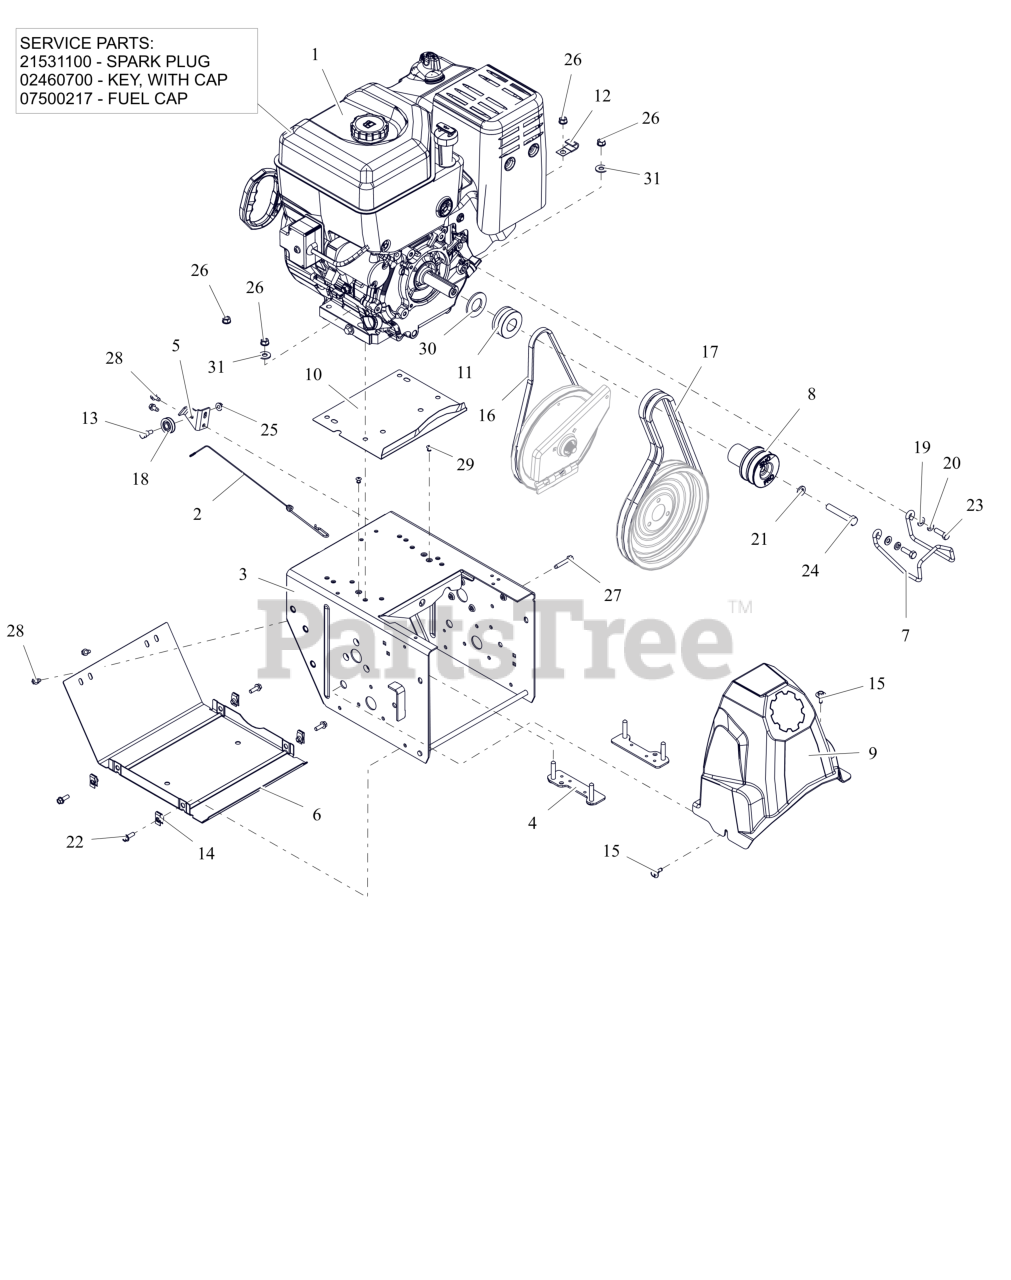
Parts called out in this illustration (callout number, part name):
1	ENGINE, BRIGGS PF 2100, 120V
1	PLUG, SPARK B&S
1	KEY -W/CAP
1	CAP, FUEL - BRIGGS & STRATTON
2	CABLE, LOWER TRACTION,SS & PRO
3	FRAME, MAIN - PRO (WELDMENT)
4	STRAP, BOLT-LARGE
5	BRACKET, CABLE PULLEY
6	COVER, BOTTOM
7	FINGER, BELT
8	SHEAVE,ATTACHMENT-SHO 2 GRV
9	COVER, BELT
10	BAFFLE, WATER - LARGE BLOCK
11	SHEAVE, TRACTION (KEYLESS)
12	J-CLAMP
13	BOLT, SHLDR -.375 X .375 X .25-20
14	NUT-RTNR .25-20X.56
15	SCR-TAP .25-20X.5 CAPTIVE
16	V-BELT, 3L-WRAPPED
17	V-BELT, HA-RAW EDGE (SET)
18	PULLEY, CABLE
19	WSHR,FLT .344X.688X.065 ZCC
20	WSHR, LK-HVY .312X.097 ZCC
21	WSHR, LK-REG .438X.109 ZCC
22	BLT, HWH .25-20X.75 G5 ZCC
23	BLT, HEX 0.3125-24X1 G5 ZCC
24	BLT, HEX .44-20X2.50 G5 ZCC
25	NUT-LK-TOP-FLG .250-20 GF ZCC
26	NUT,LK-CTR-FLG .31-18 GF ZCC
27	SCR,TAP .25-20X1.50 HWH TR ZCC
28	SCR-TAP .25-20X.50 HWH ZCC
29	RVT, POP .1875 ZCC
30	WSHR, FLT 1.062X2.000X.134 ZCC
31	WSHR,FLT .375X.875X.083 ZCC
